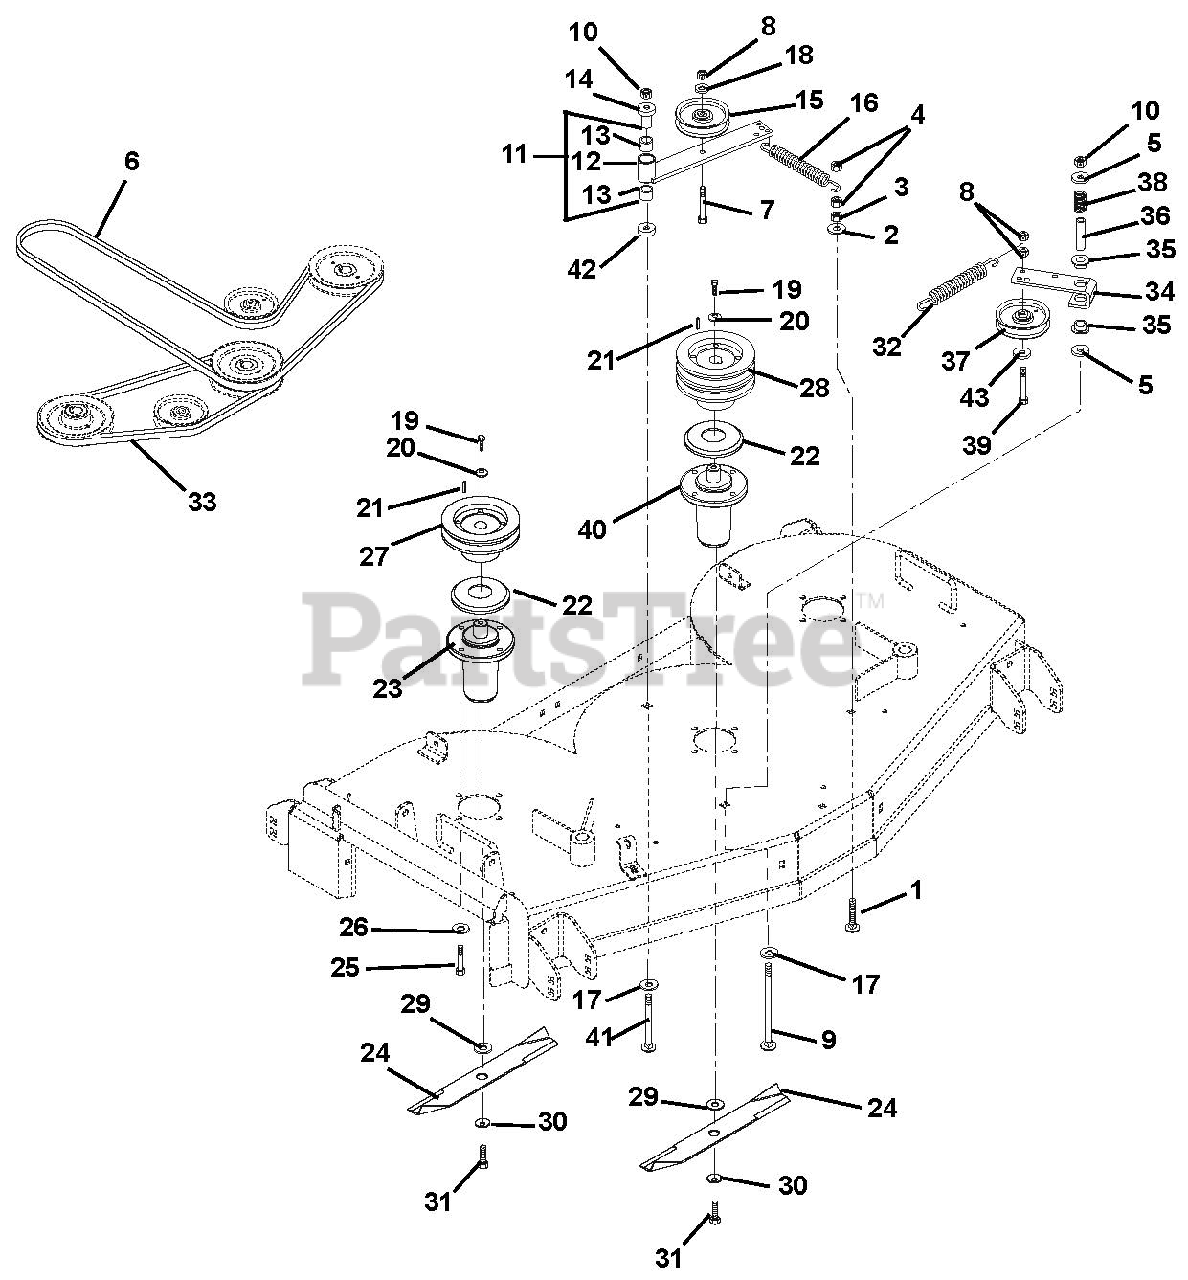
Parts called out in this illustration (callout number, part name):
1	Bolt-Round Head Square Neck .38-16 x 1.50 Grade 5
2	Washer-Locking .38 x .094 Regular
3	Nut-Hex .38-16
4	Nut-Locking-Center .38-16
5	Washer-Flat-Steel .531 x 1.25 x .10
6	V-Belt B-Section 39.38 x .65
6	V-Belt B-Section 42.25 x .65
7	Bolt-Round Head Square Neck .38-16 x 2.75 Grade 5
8	Nut-Locking-Center .38-16
9	Bolt-Round Head Square Neck .50-13 x 3.50 Grade 5
10	Nut-Locking-Center .50-13
11	Assembly, Idler Pivot Arm
12	Weldment, Idler Pivot Arm
13	Bearing, 1.00 x 1.12 x .75
14	Bearing, Pedestal Powdered Metal
15	Idler-Flat 4.00 x .38 2.00 W
16	Spring, Extension
17	Washer-Flat-Steel .755 x 1.375 x .062
18	Washer-Flat-Steel .375 x 1.125 x .065
19	Bolt-Hex .38-16 x 1.00 Grade 8
20	Washer-Cupped-Serrated .375
21	Key, Square .25 x .25 x 1.00 RC 40-50
22	Slinger-Dust
23	Assembly, Maintenance Free Spindle
24	Blade- Mower
24	Blade- Mulching
25	Bolt-Hex .38-16 x 1.00 Grade 5
26	Washer-Locking .38 x .094 Regular
27	Pulley
28	Sheave, Double 5.25
29	Washer, Flat .64 x 1.81 x .250
30	Washer-Bellville .63 x 1.625 x .14
31	Bolt-Hex .62-18 x 1.75 Grade 8
32	Spring, Extension
33	V-Belt 5L-Section 49.97 x .672
34	Arm, Idler Pivot
35	Bushing-Flange .762 x 1.00 x .58 x 1.48 Nylon
36	Spacer .56 x .75 x 2.44 Steel
37	V-Idler, 4.00 x .38
38	Spring-Compression .085 x .80 x 1.00
39	Bolt-Hex .38-16 x 2.25 Grade 5
40	Spindle Assembly, Center
41	Bolt-Round Head Square Neck .50-13 x 3.75
42	Washer-Flat-Steel .515 x 1.625 x .25
43	Washer-Flat-Steel .406 x .812 x .065
